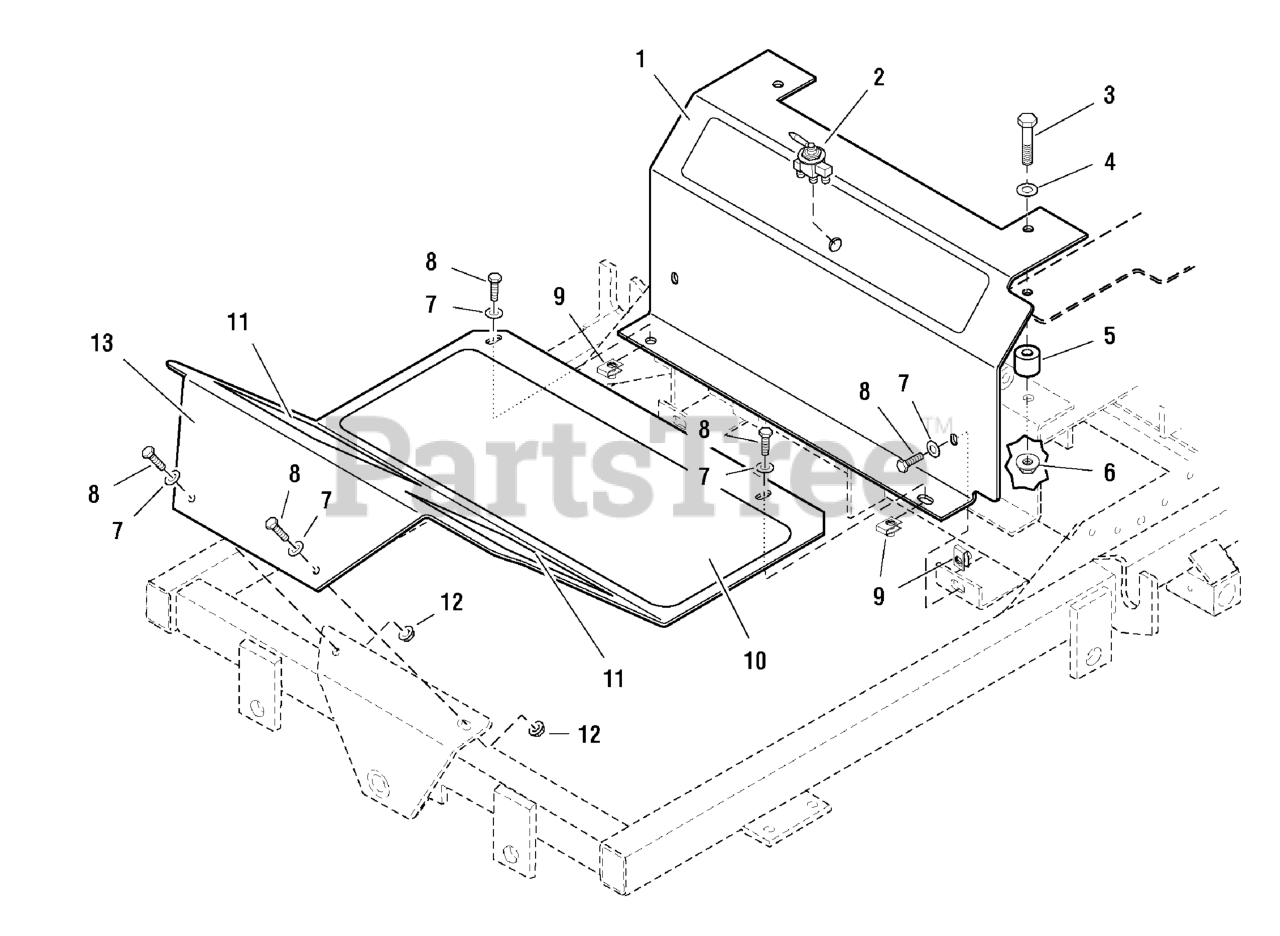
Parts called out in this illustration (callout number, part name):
1	BRAKE COVER PANEL ASSEMBLY
2	VALVE, Fuel Shut Off
3	BOLT, 3/8-16 X 2, GD5, CZ
4	WASHER, 3/8 SAE
5	SPACER, .39 x 1.00 x .88
6	NUT, 3/8-16 Hex Serrated Flange
7	WASHER, 5/16" SAE
8	BOLT, 5/16-18 X 1 GD5 YZ
9	BODY CLIP, 5/16-18-7GA MATERIAL
10	SAFETY WALK, 11.50 X 19.00
11	SAFETY WALK
12	NUT, 5/16-18 HEX SERRATED FLANGE (SMALL)
13	FLOOR PLATE
